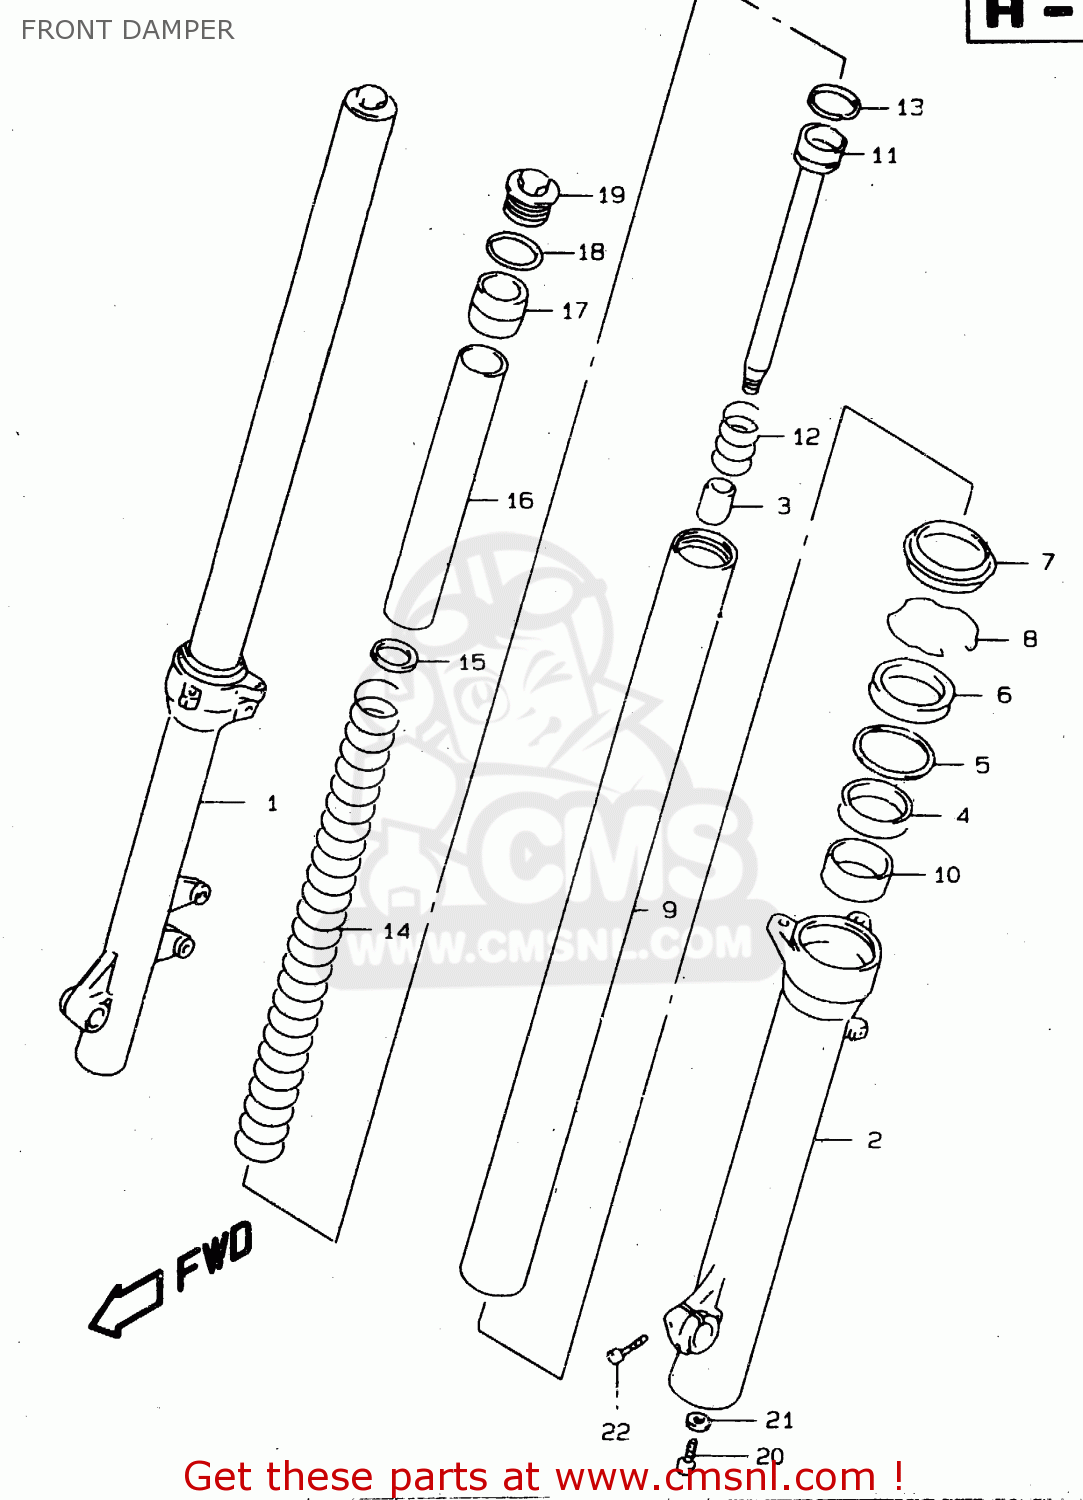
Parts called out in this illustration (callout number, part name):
1	TUBE,OUTER,R
2	TUBE,OUTER,L
3	PIECE,OIL LOCK
4	METAL,SLIDE
5	WASHER
6	SEAL,OIL
7	SEAL,DUST
8	RING,STOPPER
9	TUBE,INNER
10	PISTON
11	CYLINDER
12	SPRING,REBOUND
13	RING,PISTON
14	SPRING,FR
15	WASHER
16	SPACER
17	SPACER
18	O RING
19	CAP,FORK
20	BOLT,FORK CYLINDER(10X25)
21	GASKET (NAS)
22	BOLT,SOCKET HEAD(8X22)
